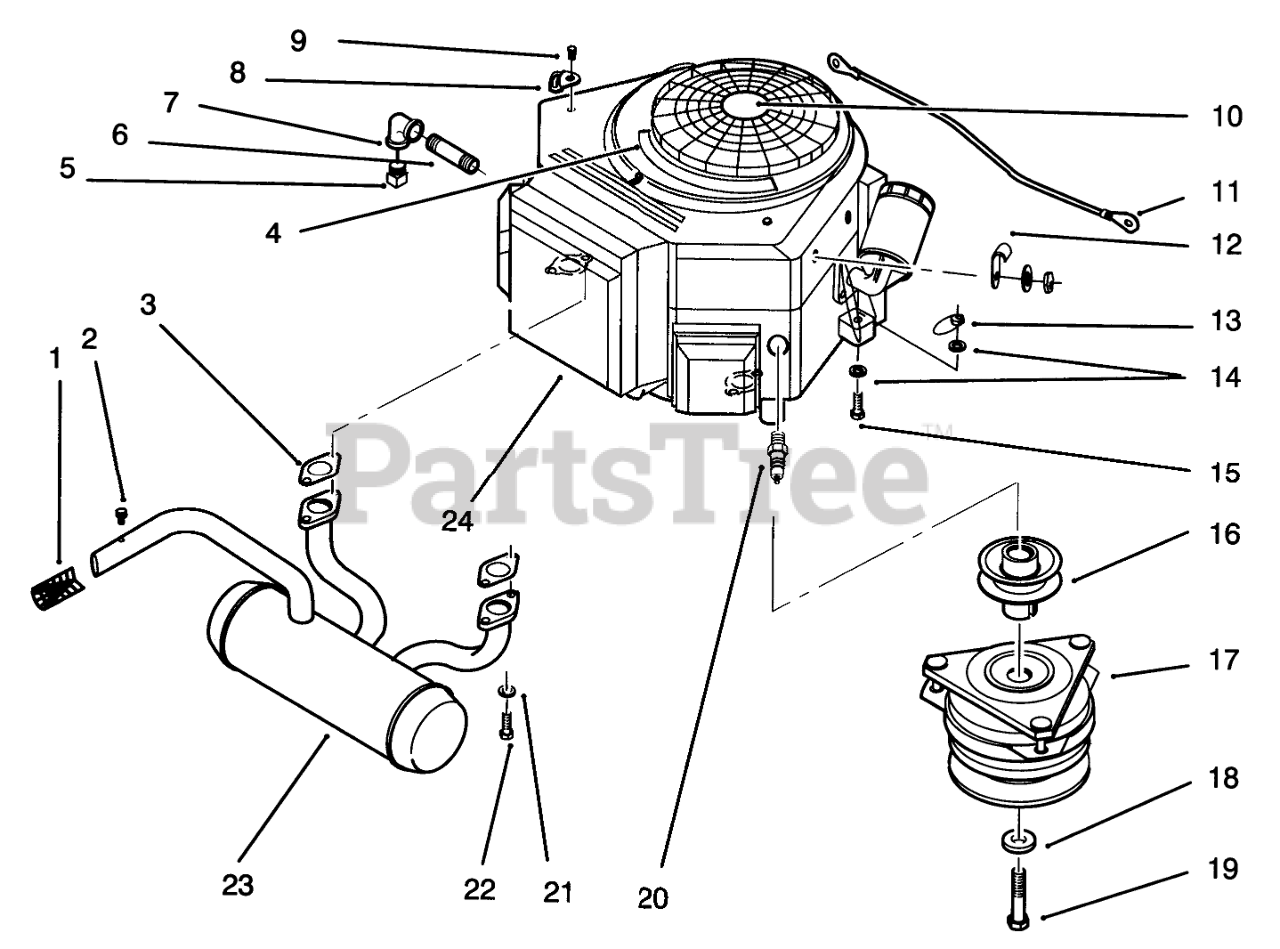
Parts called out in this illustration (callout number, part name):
1	Arrester-Spark
2	BOLT-HEX S.T. #8X1/2
3	GASKET-MUFFLER
4	DECAL - POWER PLUS
5	PLUG-PIPE, SQH
6	NIPPLE-PIPE
7	ELBOW 3/8 90 DEG
8	CLEVIS
9	Screw
10	DECAL-TORO ENGINE
11	Wire-Starter to Solenoid
12	J-CLIP
13	NUT-LOCK, NI
14	WASHER-PLAIN
15	SCREW-HH
16	PULLEY-ENGINE HYD R
17	Clutch
18	WASHER
19	SCREW-HH
20	SPARK PLUG
21	WASHER-LOCK
22	SHCS 5/16-18X.625
23	MUFFLER
24	Engine
